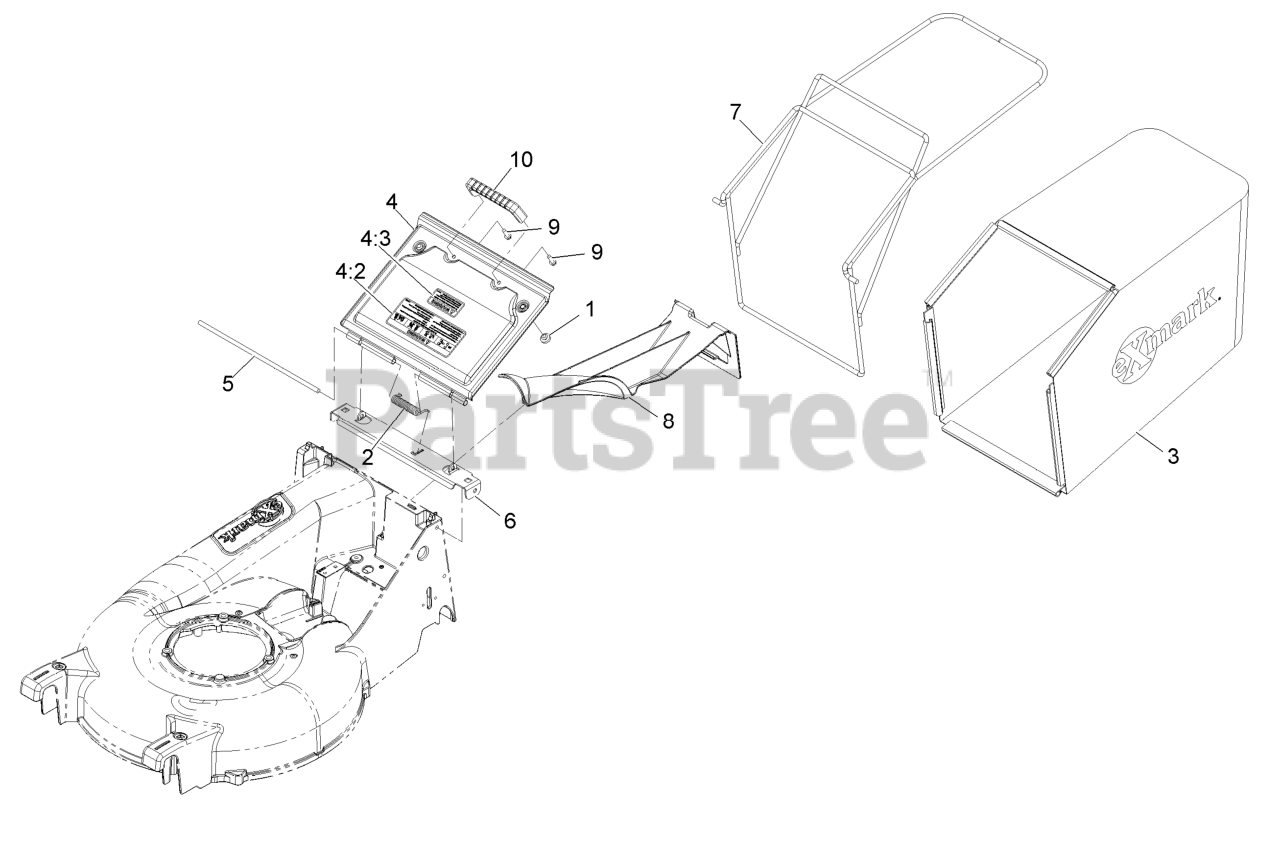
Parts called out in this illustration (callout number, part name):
2	SPRING-TORSION,COVER
3	BAG,GRASS P21
4	DOOR W/DECAL
4:2	DECAL-WARNING
4:3	DECAL-WARNING DOOR SM
5	ROD,DOOR PIVOT
6	BRACKET-DOOR P21
7	WLD,BAG FRAME
8	PLUG,MULCH
9	SCREW-HWH
10	HANDLE-DOOR
